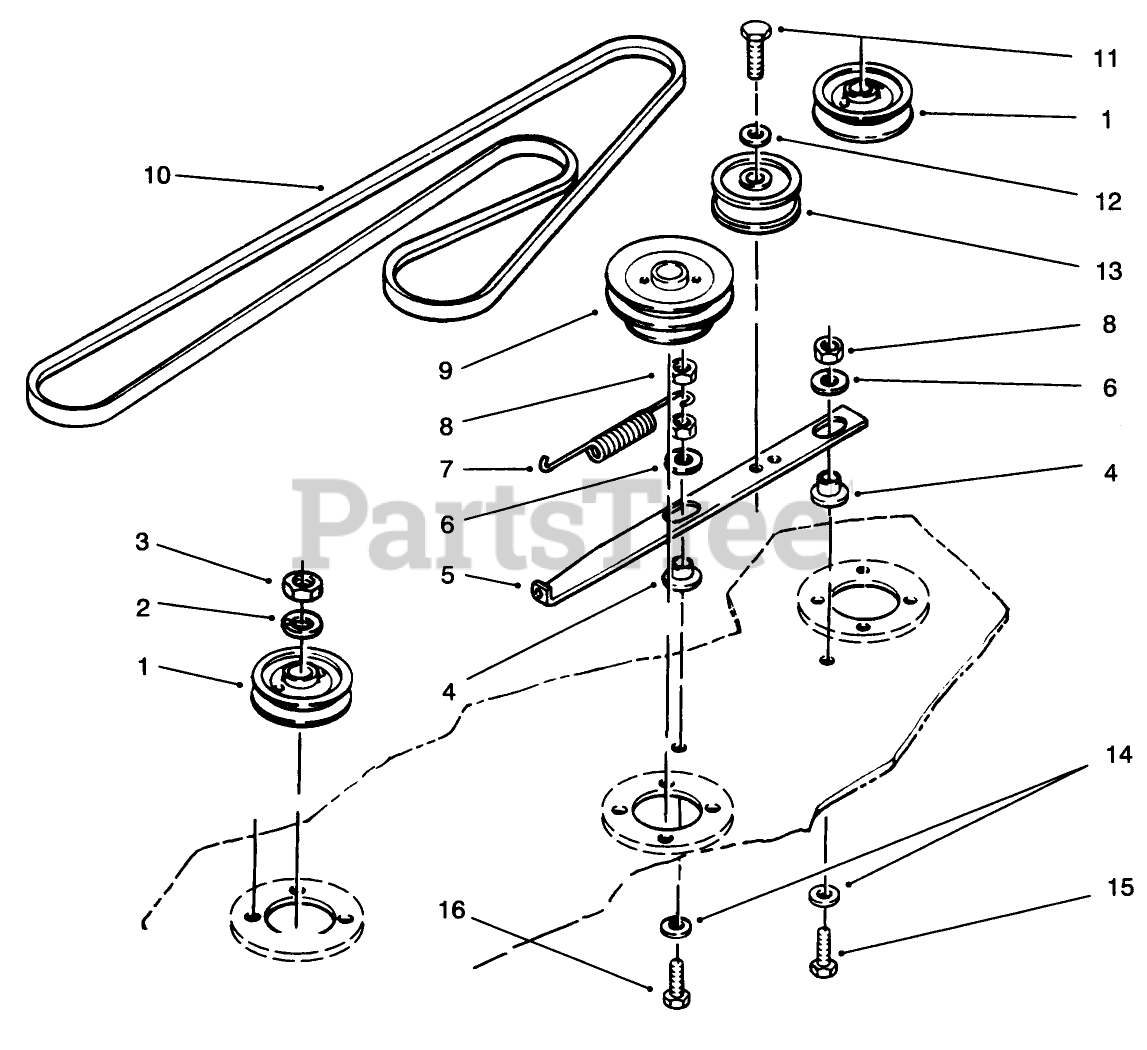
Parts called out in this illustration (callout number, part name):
1	PULLEY
2	WASHER-LOCK
3	NUT-JAM
4	SPACER-BUSHING
5	BAR-IDLER SUPPORT
6	WASHER
7	SPRING-EXTENSION
8	NUT-LOCK, NI
9	PULLEY
10	V-BELT
11	SCREW-HH
12	WASHER-LOCK
13	PULLEY-IDLER, FLAT
14	WASHER
15	SCREW-HH
16	SCREW-HH
